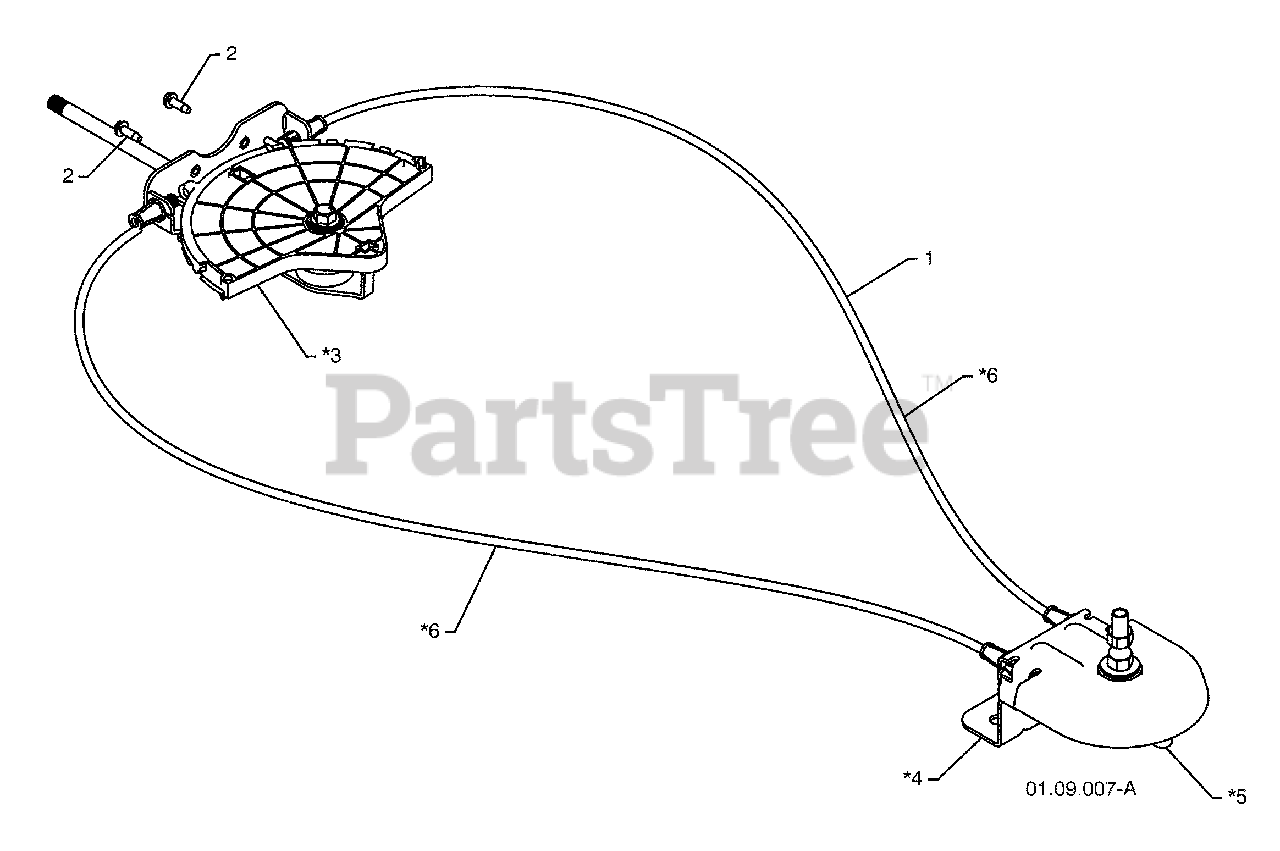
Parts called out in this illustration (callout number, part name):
1	LEVER/CABLE ROTATOR ASSEMBLY
2	SCREW 10--24 X .625
3	ROTATOR HEAD
4	ROTATOR PIVOT BRACKET
5	PULLEY PIVOT
6	CABLE ASSEMBLY
